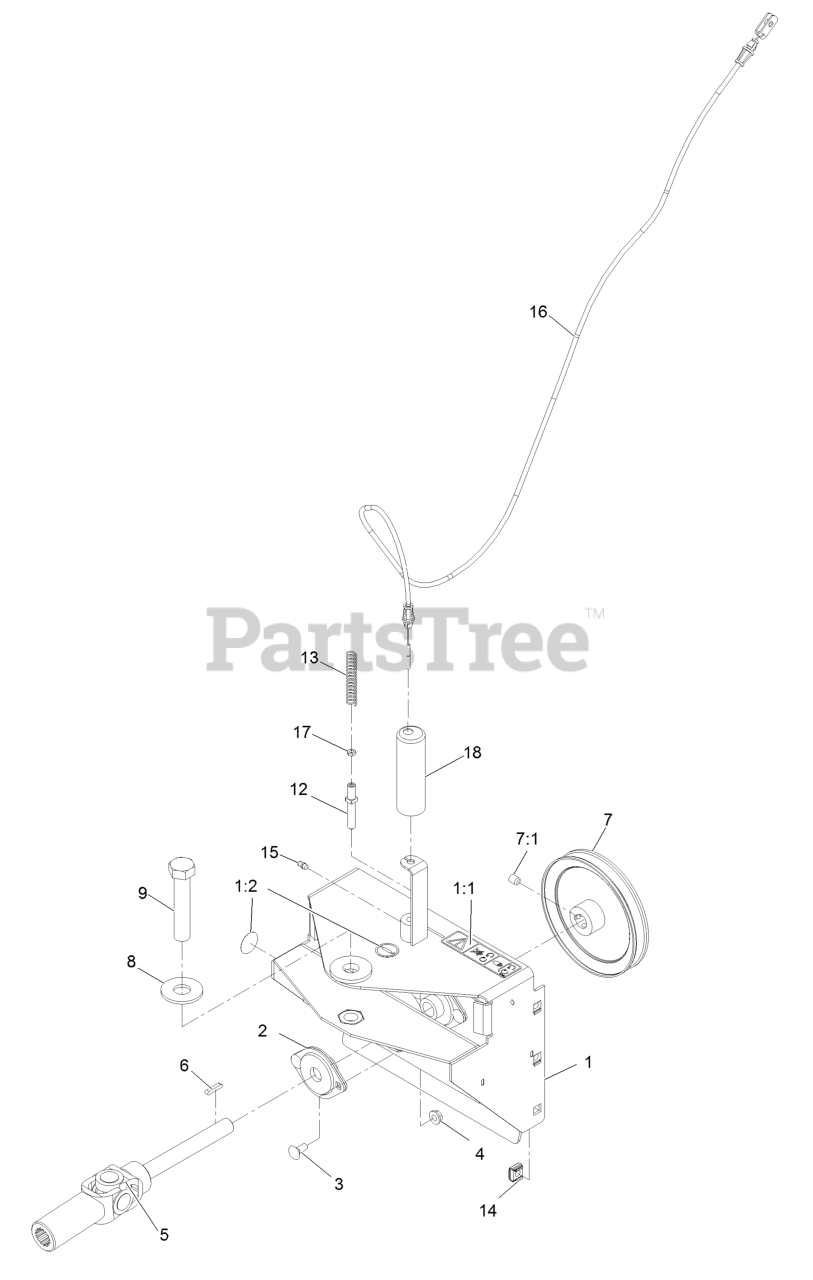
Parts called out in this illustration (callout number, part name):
1	BROOM MOUNTING FRAME ASM
1:1	DECAL-COVER, MISSING
1:2	DECAL-GREASE
2	BEARING-SHAFT
3	BOLT-CARR
5	SHAFT-DRIVE
6	KEY-ROUND END
7	PULLEY-IMPELLER
7:1	SETSCREW
8	WASHER-FLAT
9	SCREW-HH
12	PIN-SWING
13	SPRING-COMPRESSION
14	NUT-RETAINER
15	FITTING-GREASE
16	CABLE-ANGLE, BROOM
17	NUT-HEX
